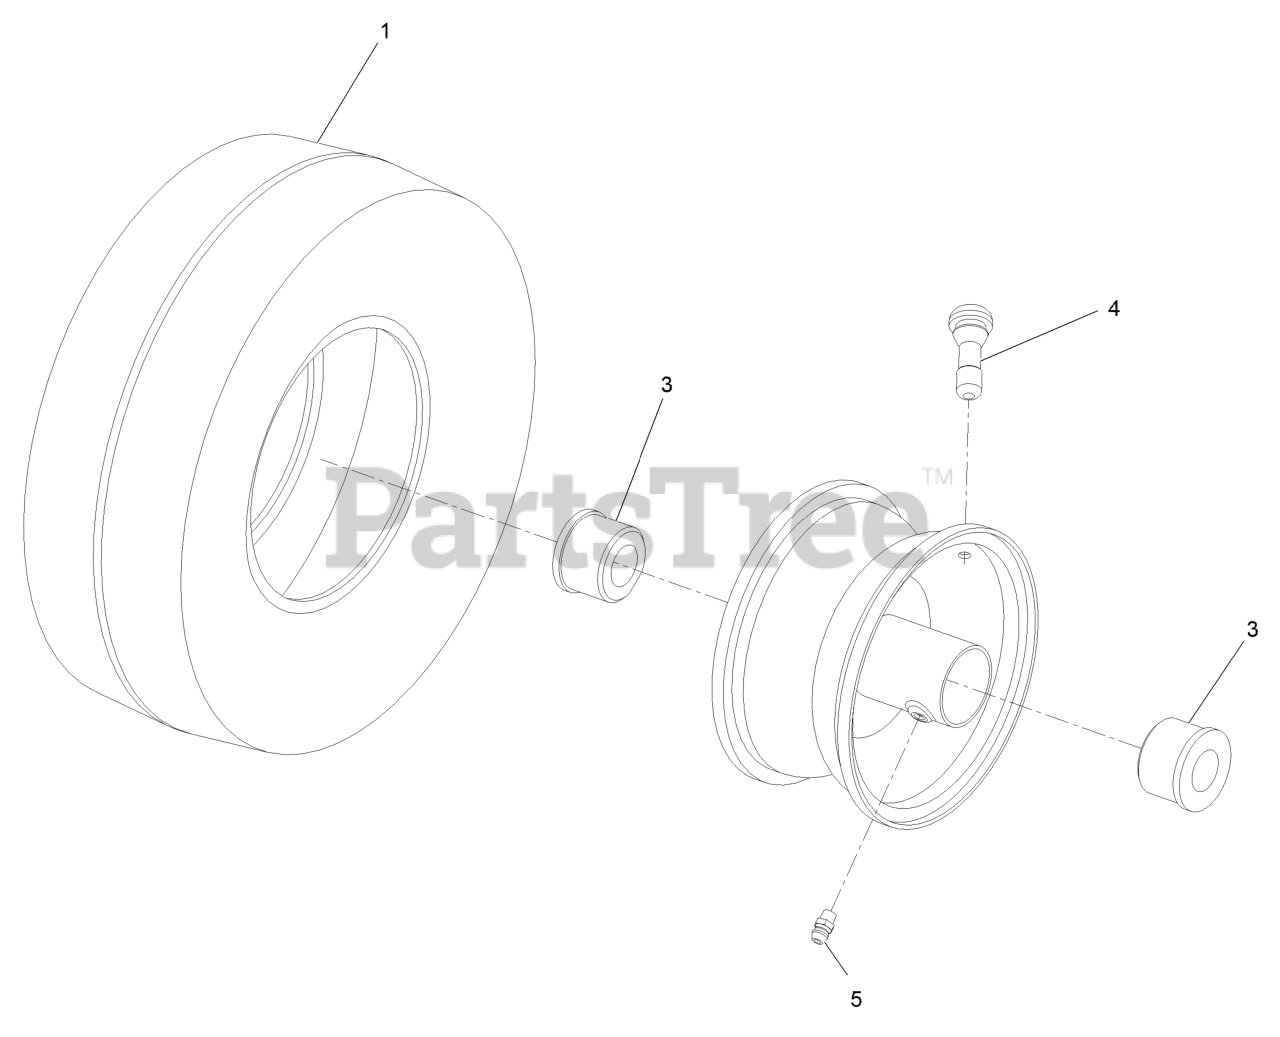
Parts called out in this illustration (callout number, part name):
3	BUSHING-FLANGE
4	Stem-Valve
5	FITTING-GREASE
